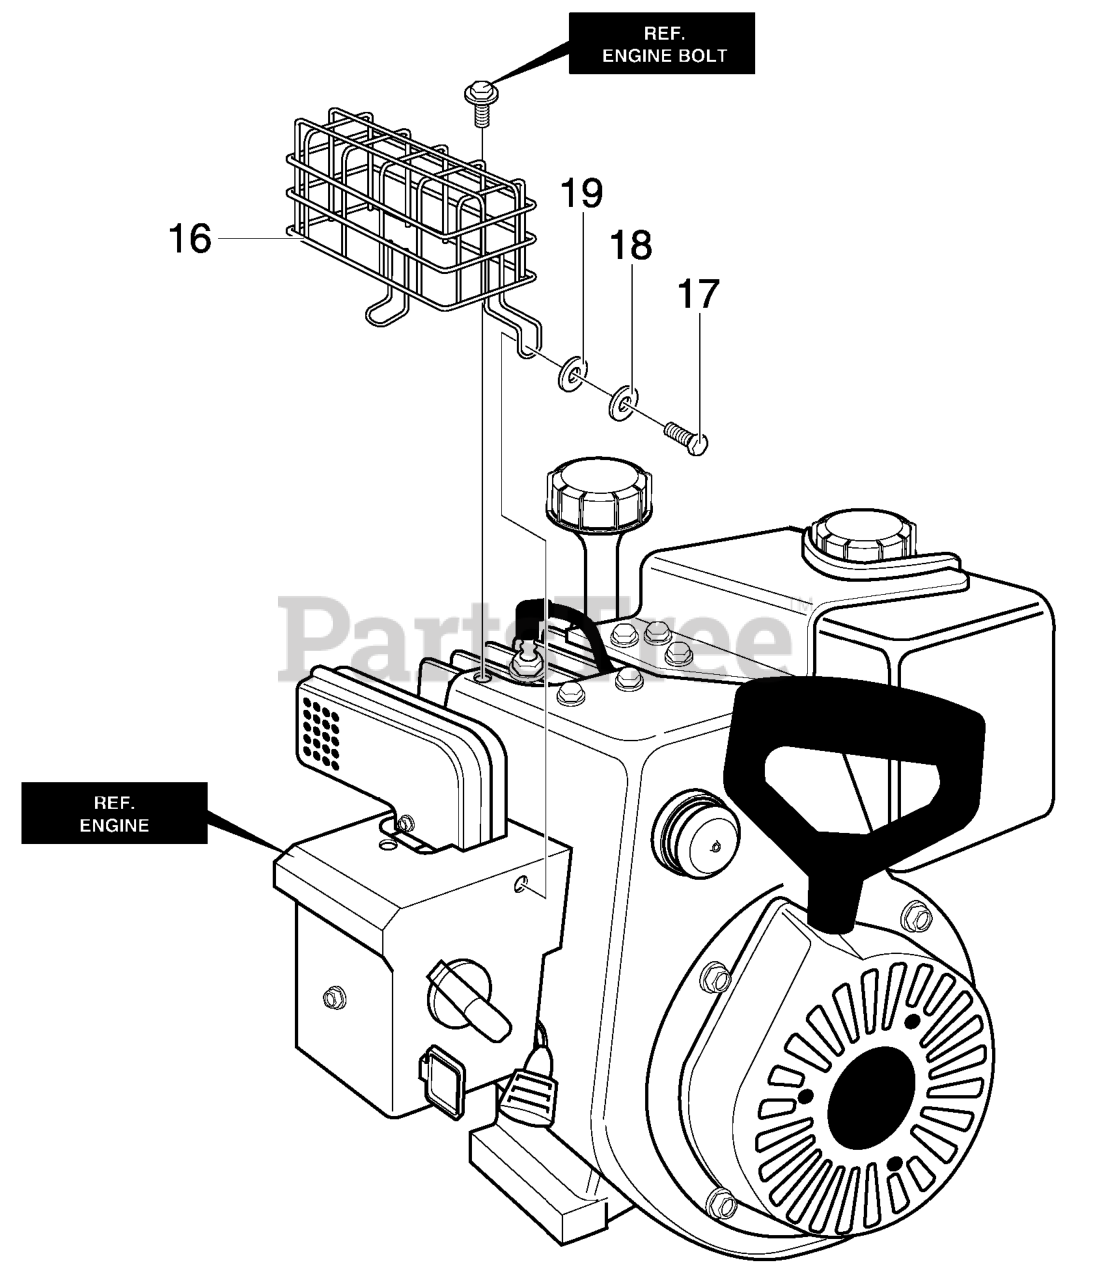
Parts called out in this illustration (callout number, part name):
16	GUARD, MUFFLER
18	WASHER
19	WASHER
